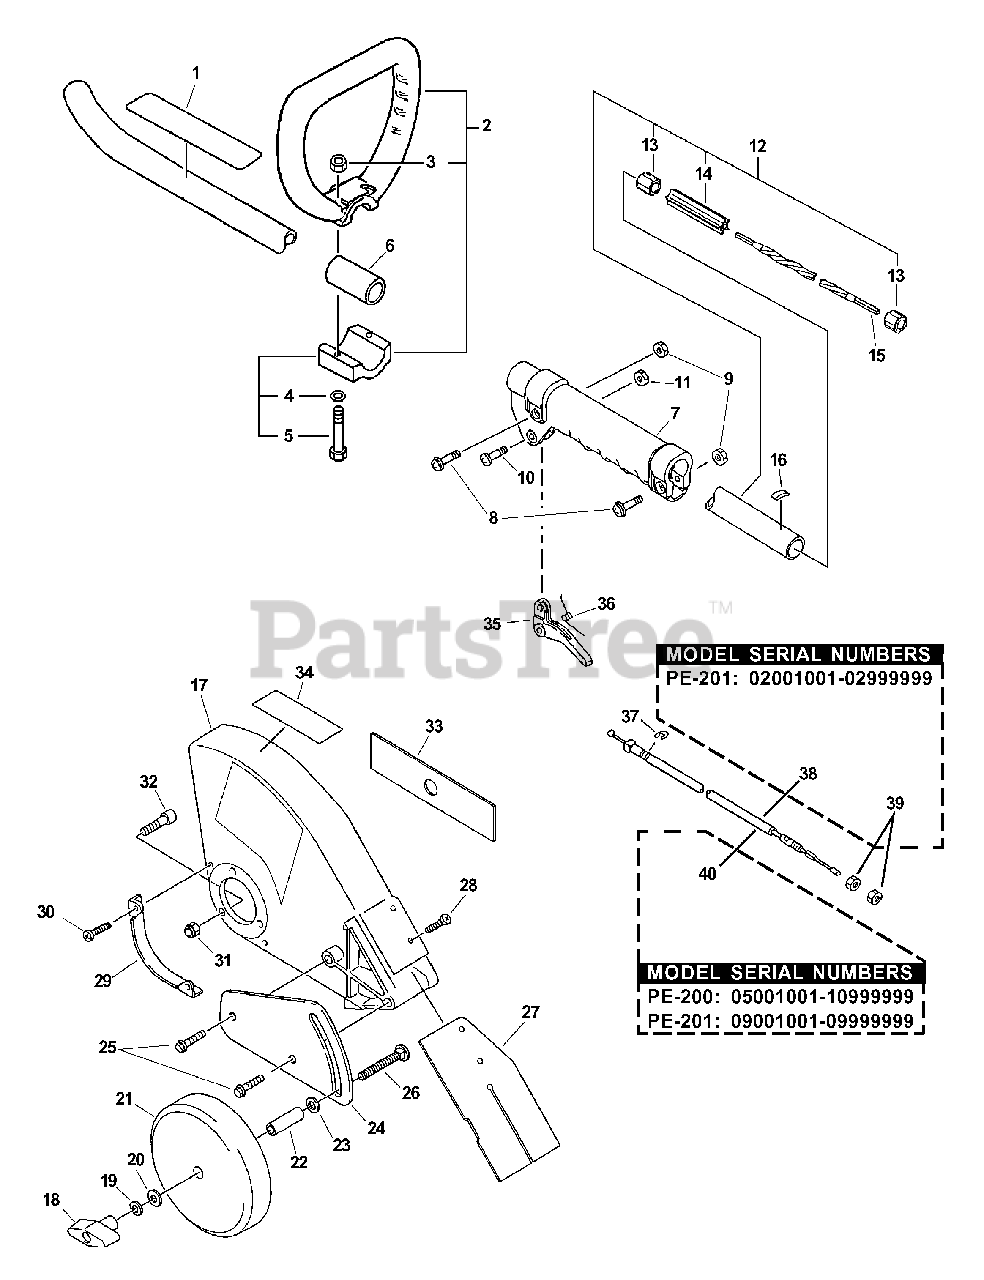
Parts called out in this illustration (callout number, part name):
1	LABEL - CAUTION
2	LOOP HANDLE ASSY
4	WASHER - 5
5	SCREW - 5X40
7	GRIP, HANDLE
8	SCREW - 5X25
10	SCREW - 5X30
11	LOCKNUT - 5
12	MAIN PIPE ASSY
14	LINER - FLEXIBLE
15	DRIVESHAFT - FLEXIBLE
16	LABEL - ALIGNMENT
17	SHIELD, DEBRIS
18	WINGNUT - 5/16-18
19	LOCKWASHER - 8
20	WASHER - 8
21	WHEEL - 6X1.5
22	COLLAR - 12
23	WASHER - 10
24	BRACKET, WHEEL
25	BOLT - 8
26	BOLT - CARRIAGE
27	FLAP, DEBRIS
28	SCREW - 3
30	SCREW - 4X16
31	LOCKNUT - 5
32	SCREW - 5X22
33	BLADE, EDGER
34	LABEL - CAUTION -- SPANISH
35	TRIGGER, THROTTLE
36	SPRING, TRIGGER
37	RING, RETAINING - 5
38	CABLE, THROTTLE
39	NUT - 6
40	CABLE, THROTTLE
